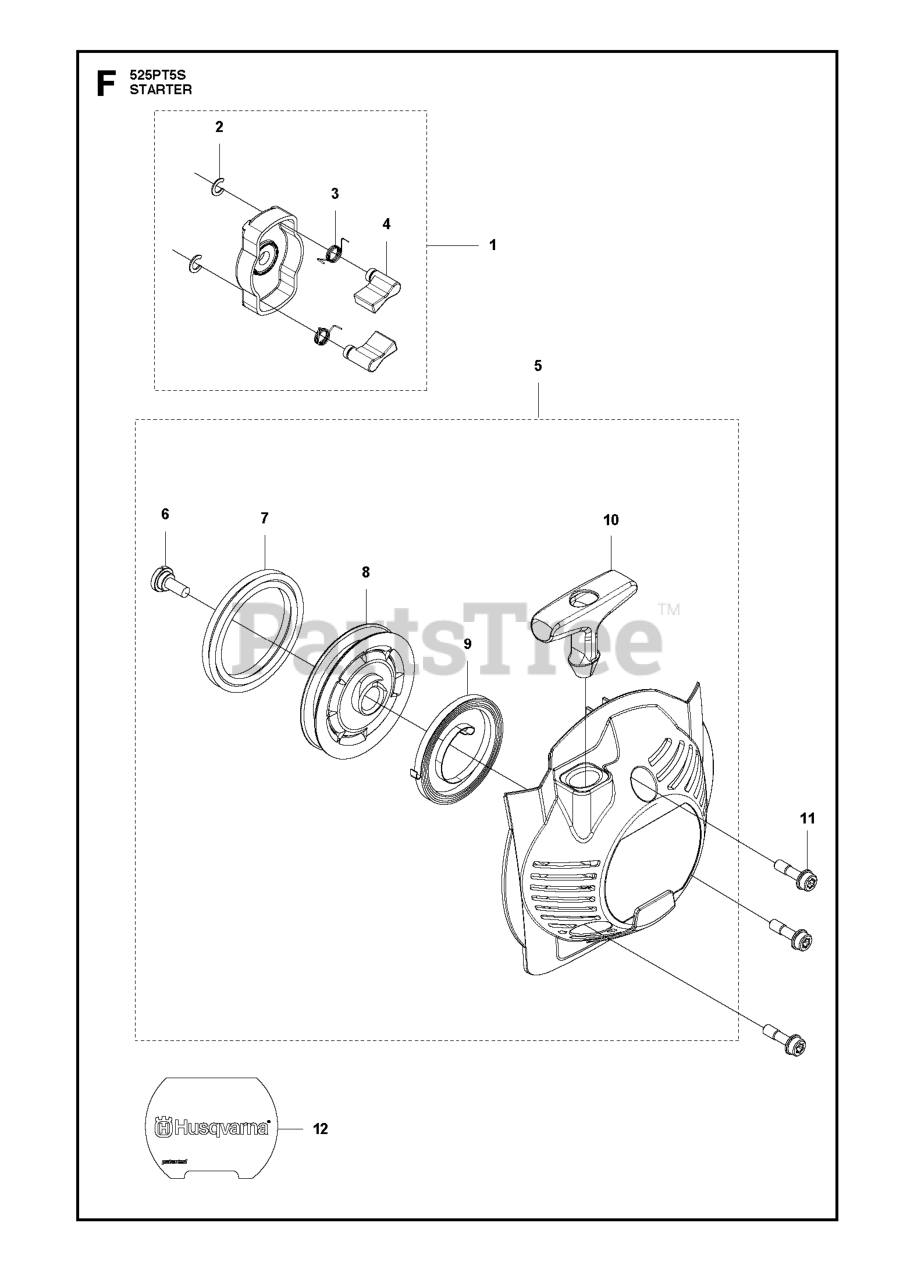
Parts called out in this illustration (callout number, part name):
1	STARTER PULLEY ASSY
5	STARTER ASSY
6	SCREW
8	STARTER PULLEY
9	SPRING, SPIRAL
10	STARTER HANDLE
11	BOLT
12	DECAL STARTER
